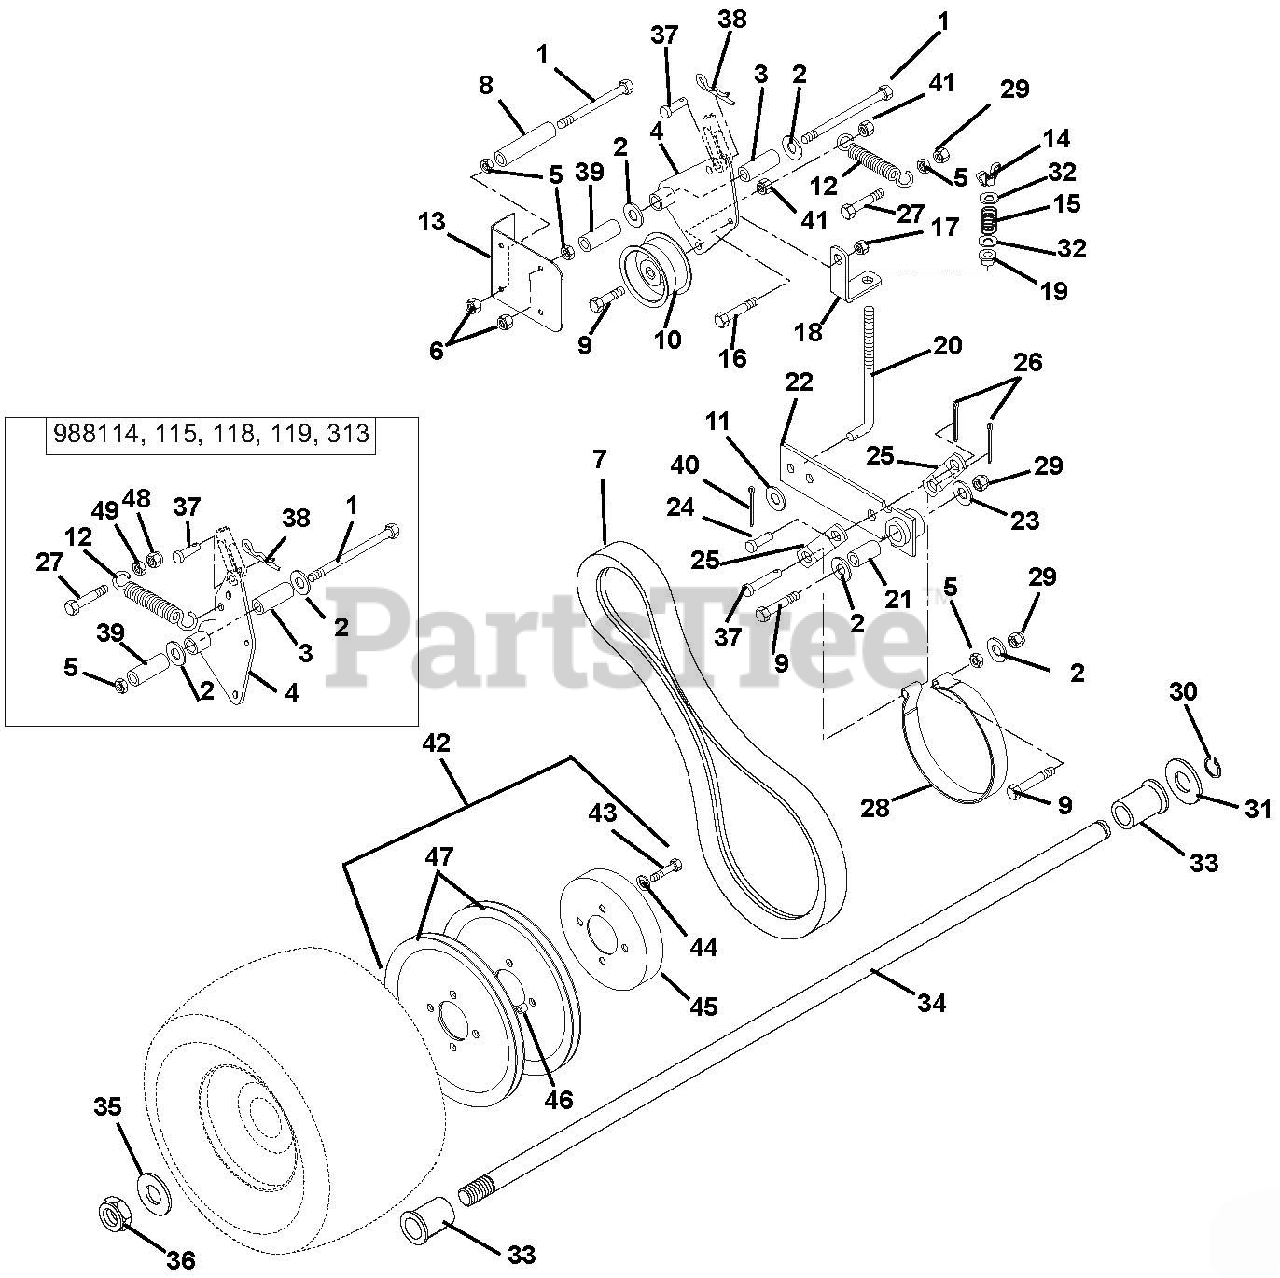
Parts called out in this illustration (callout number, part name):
1	Bolt-Hex .38-16 x 4.50 Grade 5
2	Washer-Flat-Steel .406 x .812 x .065
3	Bushing, Steel .385 x .610 x 1.80
4	Weldment- Wheel Clutch Arm
5	Nut-Hex .38-16
6	Nut-Locking-Flange .375-16
7	Belt, Traction Drive
8	Bushing, Spacer, 3.25 x .38 I.D. x .63 O.D.
9	Bolt-Hex .38-16 x 2.00 Grade 5
10	Sheave 3.25 x 1.25
11	Washer-Flat-Steel .344 x .688 x .065
12	Spring-Tension .105 x 1.00 x 5.00
13	Kit-Belt Cover with Decals
14	Nut-Nylock Wing .31-18
15	Spring-Compression .125 x .78 x 1.00
16	Bolt-Hex .25-20 x .75 Grade 5
17	Nut-Locking-Nylon .25-20
18	Bracket, Brake Link
19	Bushing-Flange .32 x .62 x .312 Nylon
20	Rod, Brake
21	Bushing Sleeve .39 x .622 x .95 Steel
22	Weldment, Brake Arm
23	Washer-Flat-Steel .406 x 1.00 x .188
24	Pin-Clevis .38 x .75
25	Link, Brake Arm
26	Pin-Cotter .12 x .75
27	Bolt-Hex .38-16 x 1.50 Grade 5
27	Bolt-Hex .31-18 x 2.00 Grade 5
28	Assembly, Pro Brake Band
29	Nut-Locking-Nylon .38-16
30	Ring-Retaining-External .906 x .078
31	Washer-Flat-Steel 1.01 x 1.50 x .062
32	Washer-Flat-Steel .38 x .875 x .083
33	Bushing-Flange 1.01 x 1.38 x 1.4 x 1.65
34	Shaft, Axle
35	Washer-Flat-Steel .812 x 1.50 x .135
36	Nut-Locking-Jam-Nylon .75-10
37	Pin-Clevis .38 x 1.25
38	Pin-Hair Internal .08 x .18 x 1.18
39	Bushing, Spacer
40	Pin-Cotter .09 x .75
41	Nut-Locking-Jam-Center .38-16
42	Assembly, Pulley and Drum
43	Bolt-Hex .31-18 x 1.50 Grade 5
44	Washer-Locking .31 x .078 Regular
45	Drum, Brake
46	Bushing, Sleeve .385 x .625 x .475 Steel
47	Sheave 8"
48	Nut-Locking-Center .31-18
49	Nut-Hex .31-18
